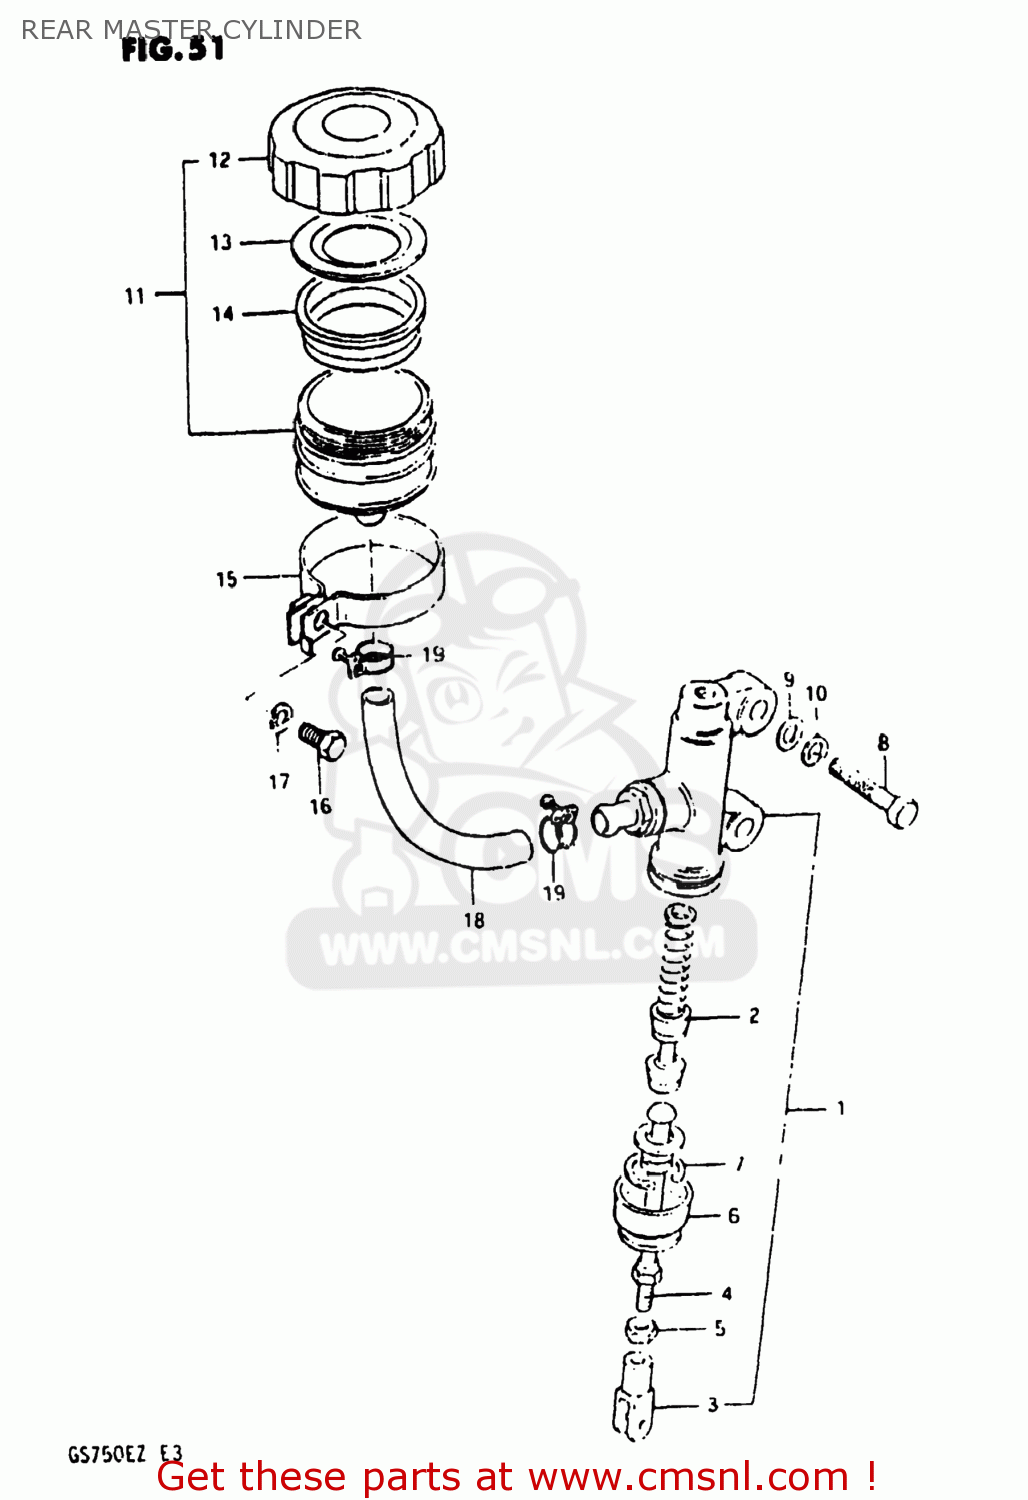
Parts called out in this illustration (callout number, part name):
1	CYLINDER ASSEMBLY,REAR MASTER
2	PISTON/CUP SET
3	YOKE
4	ROD,PUSH
5	NUT,MASTER CYLINDER
6	BOOT
7	CIRCLIP
8	BOLT (8X30)
9	WASHER
10	LOCK WASHER
11	TANK ASSEMBLY,RESERVOIR
12	CAP
13	PLATE,DIAPHRAGM
14	DIAPHRAGM
15	CLAMP
16	BOLT, UPPER
17	LOCK WASHER
18	HOSE,RESERVOIR TANK
19	CLAMP
